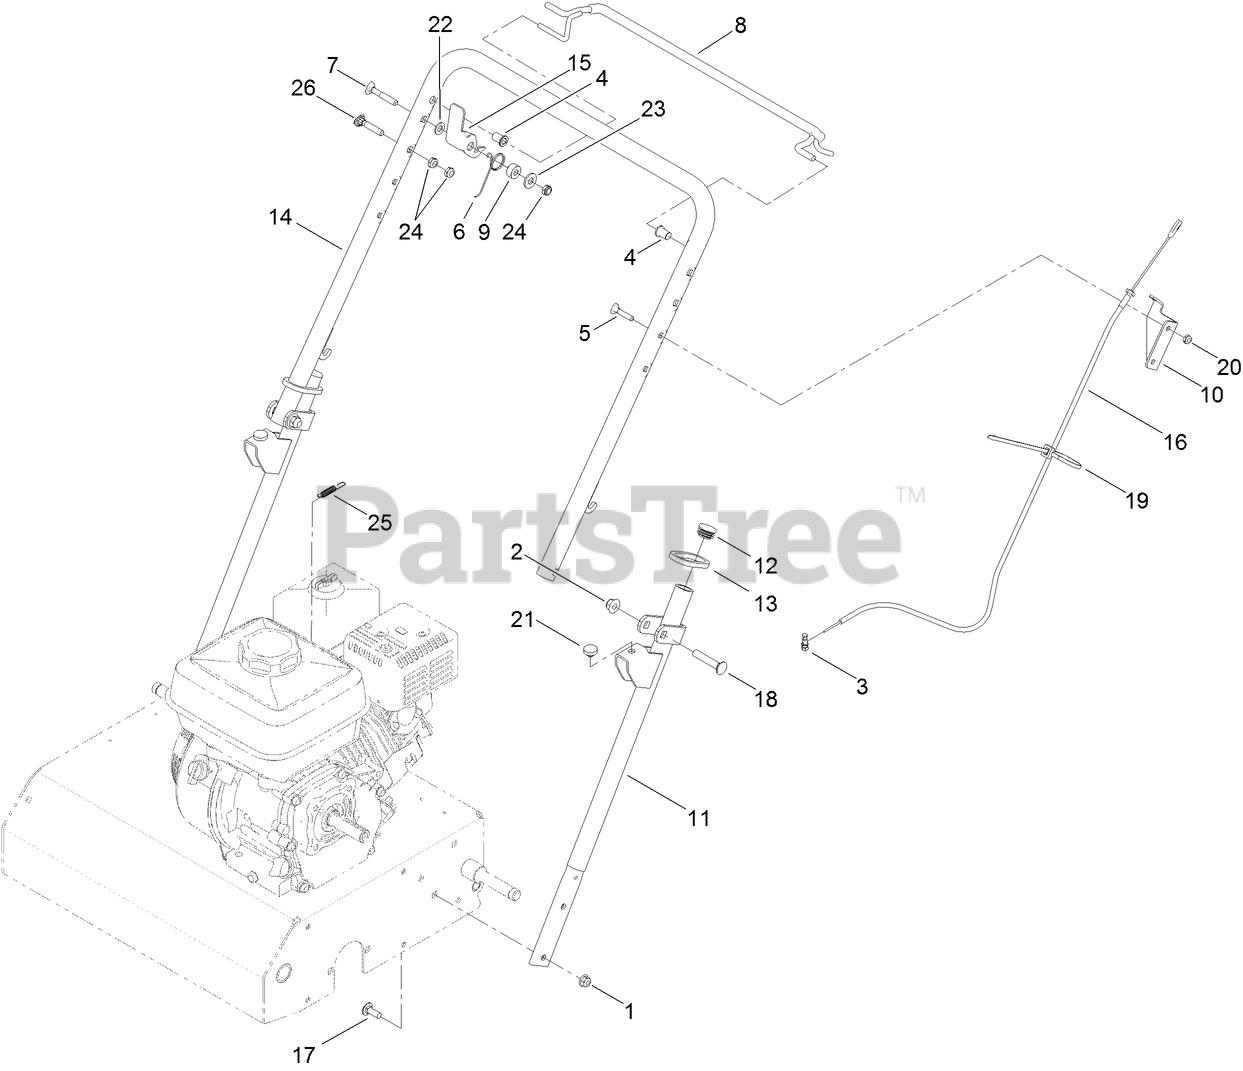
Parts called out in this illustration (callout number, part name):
1	NUT-HF, NI
2	NUT-HF, NI
3	SWIVEL-STOP, CABLE
4	BUSHING
5	BOLT-HANDLE
6	SPRING, LOCK-TAB
7	SCREW-HANDLE
8	BAIL-TRACTION
9	BUSHING-STEPPED
10	BRACKET-CABLE, THROTTLE
11	HANDLE-LOWER
13	RING-HANDLE LOCK
14	HANDLE-UPPER
15	TAB-LOCK
16	CABLE-THROTTLE
17	BOLT-CARR
18	SCREW-CARR
19	TIE-CABLE
20	NUT-LOCK, NI
21	BUMPER
22	WASHER-PLAIN
23	WASHER-FLAT
24	NUT-LOCK, NI
25	SPRING-EXTENSION
26	SCREW-HANDLE
